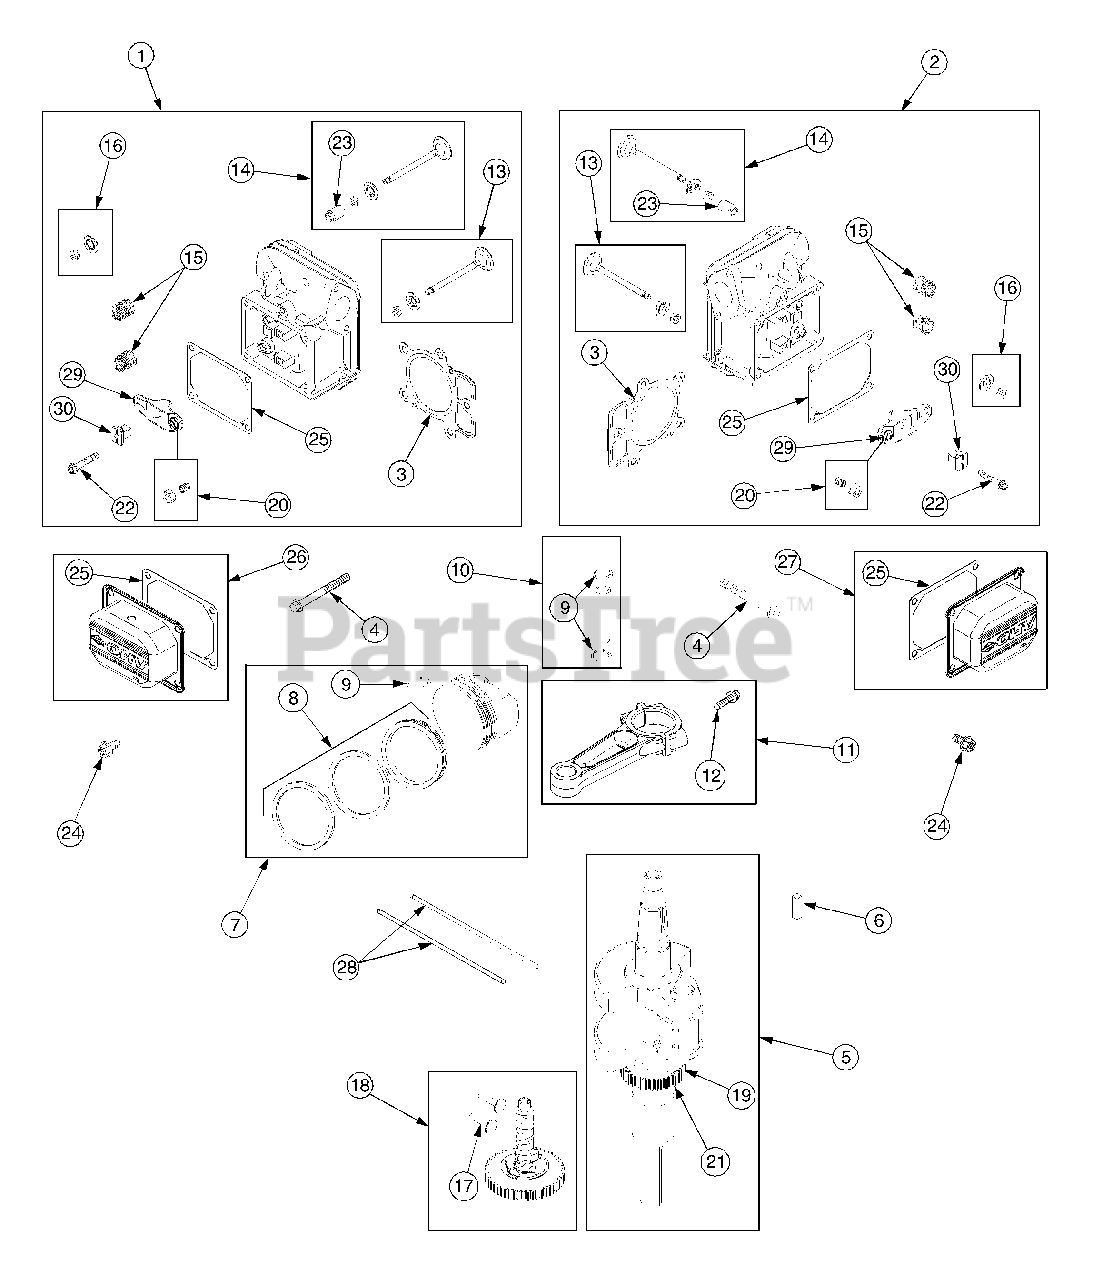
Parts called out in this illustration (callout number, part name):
1	Head, Cylinder (Cylinder 1)
2	Head, Cylinder (Cylinder 2)
3	Gasket, Cylinder Head
4	Screw, (Cylinder Head)
5	Crankshaft
6	Key, Flywheel
7	Piston Assembly (Standard)
8	Ring Set, Piston (Standard)
9	Lock Ring, Piston Pin
10	Pin, Piston
11	Rod, Connecting
12	Screw (Connecting Rod)
13	Valve, Exhaust
14	Valve, Intake
15	Spring, Valve
16	Keeper, Valve
17	Tappet, Valve
18	Camshaft
19	Key, Timing
20	Adjuster, Rocker Arm
21	Gear, Timing
22	Screw (Rocker Arm)
23	Seal, Valve
24	Screw (Rocker Cover)
25	Gasket, Rocker Cover
26	Cover, Rocker (Cylinder 1)
27	Cover, Rocker (Cylinder 2)
28	Rod, Push (Steel)
29	Arm, Rocker
30	Pivot, Rocker Arm
